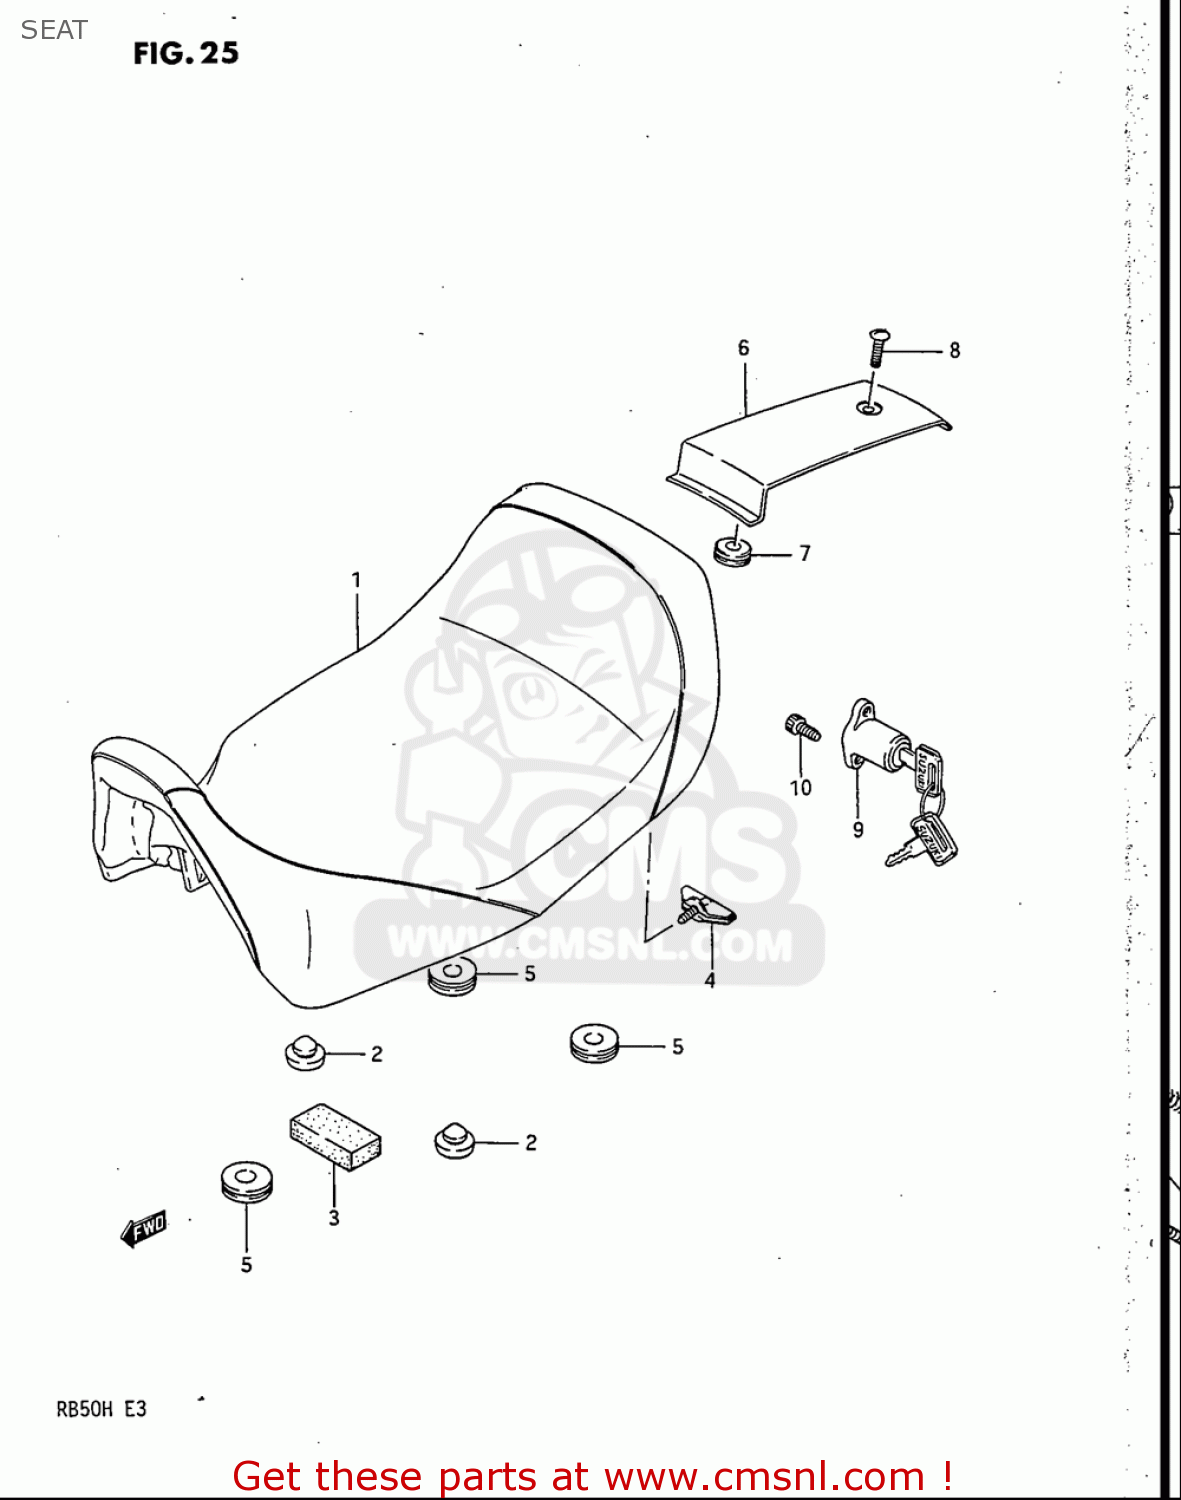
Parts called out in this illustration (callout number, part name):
1	SEAT ASSEMBLY (BLACK)
2	CUSHION
4	BOLT
5	CUSHION
6	COVER,SEAT TAIL
7	CUSHION
8	SCREW (L:20)
9	LOCK SET,HELMET
10	BOLT,VAC.PIPE
